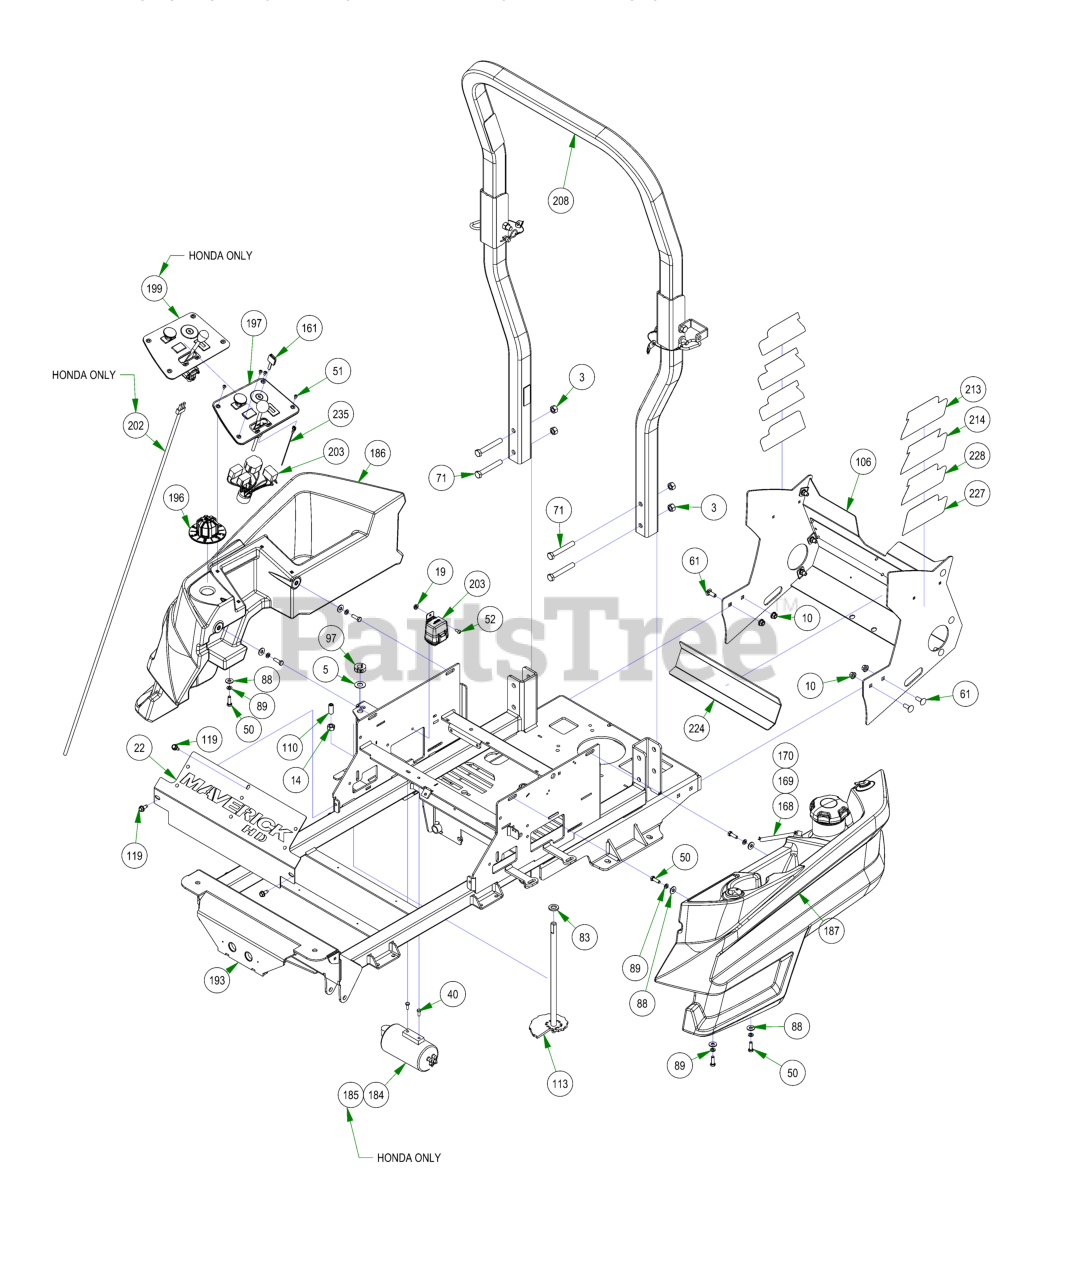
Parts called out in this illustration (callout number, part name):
3	1/2-13 HEX 2-WAY REVERSIBLE CENTER LOCKNUT Grade B ZINC
5	.625 ID x 1.250 OD x .062 THK F/W Nylon
10	3/8-16 NYLON INSERT FLANGE LOCKNUT (GR.F) ZINC
14	1/2-13 HEX NUT ZINC
19	1/4-20 HEX SERRATED FLANGE NUT HARD/ZINC
22	Maverick HD Cooler Cover
40	M6-1.0 X 16MM DIN 933 HEX TAP BOLT (CL 8.8) ZINC
50	5/16-18 X 1 HEX CAP SCREW (GR.5) ZINC
51	10-32 X 3/8 BUTTON SOCKET CAP SCREW 18-8 STAINLESS
52	1/4-20 X 1/2 BUTTON SOCKET CAP SCREW 18-8 STAINLESS
61	3/8-16 X 1 CARRIAGE BOLT (GR.5) ZINC
71	1/2-13 X 3-1/2 HEX CAP SCREW (GR.5) ZINC
83	.635 ID X 1.120 OD X .140 THICK FLAT WASHER NYLON
88	5/16 USS FLAT WASHER (7/8 OD) ZINC
89	5/16 SPLIT LOCKWASHER ZINC
97	5/8" Split Collar
106	2022 Maverick Rear Cover Assembly
110	Dial Rod Plunger
113	ZT Deck Height Bar Assembly
119	5/16-18 X 3/4HEX WASHER SLOT (F) TCS ZINC
161	Ignition Key
168	15" Fuel Line Assembly
169	Honda Maverick Fuel Line Assembly
170	37" Fuel Line Assembly
184	ZT/Mav EPA Cannister Assy
185	2019 Honda Maverick EPA Cannister Assy
186	2021 Maverick Right Side Tank
187	2021 Maverick Left Side Tank
193	2022 Maverick Frame - Painted
196	MZ/ZT Deck Height Dial
197	2019 ZT/Maverick Control Panel Assembly
199	2022 Maverick HD Honda Control Panel Assembly
202	Honda E-Throttle Adapter
203	Wiring Harness
208	2016 2x2 ROPS
213	2022 Maverick 726cc Backplate Cluster
214	MAV HD/kohler bkplt decal
224	Heat Shield (Fiberglass Adhesive)
227	Honda Maverick HD 688cc Series Backplate Cluster
228	MavHD Honda 779cc Back Plate Decal
235	2017 MZ/ZT/MAV Tach Wire Assy
